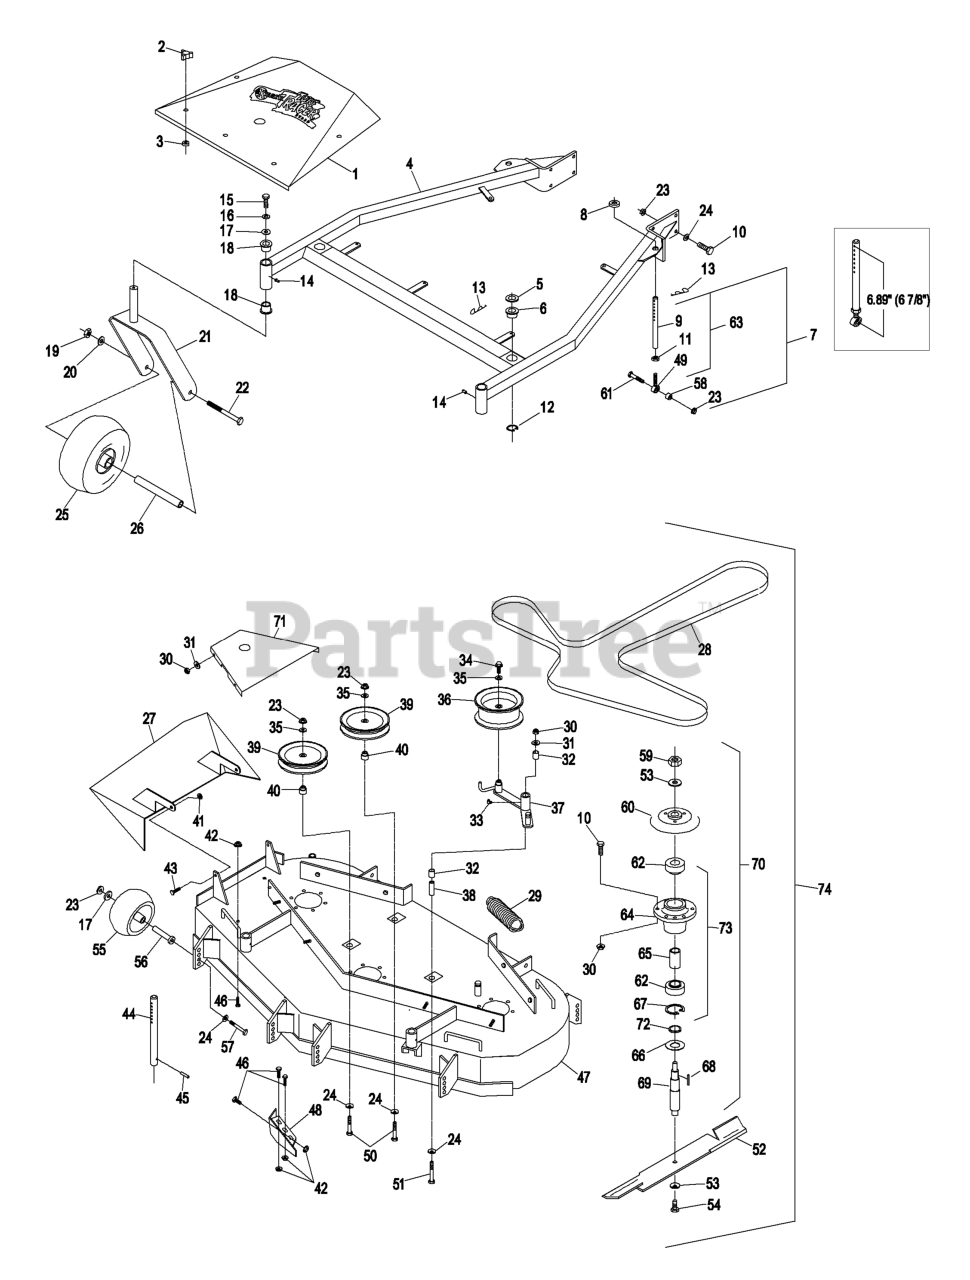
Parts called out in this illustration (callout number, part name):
2	KNOB-3 PRONG
4	SUPPORT,DECK W/BUSHINGS
5	SPACER-DECK SUPPORT
6	BUSHING-DECK
9	LINK,SUPPORT
10	SCREW-HH
11	NUT-HEX
12	RING-RETAINING
13	PIN,HAIR COTTER
14	FITTING-GREASE
15	SCREW-HH
16	WASHER-LOCK
18	BEARING-FLANGED
19	NUT-HH
20	WASHER-LOCK
22	SCREW-HH
23	NUT-HHF, WHIZ
24	WASHER-BELLEVILLE
27	WLD,CHUTE DISCHARGE
28	BELT,DECK DRIVE
30	NUT-LOCK, NI
31	WASHER-FLAT
32	SLEEVE-BEARING
33	FITTING-GREASE, 90 DEG
34	SCREW-HHF
35	WASHER-FLAT
38	BUSHING-PIVOT, IDLER
39	PULLEY-IDLER
40	BUSHING-IDLER
41	NUT-LOCK, NI
43	SCREW-HH
44	ROD,DECK SUPPORT
46	SCREW-HH
47	ASM,DECK W/DECALS TTHP52
48	WLD,BAFFLE DISCHARGE
49	BALLJOINT
50	SCREW-HH
51	SCREW-HH
53	WASHER-SPRING
54	SCREW-CAP
55	ROLLER-SCALP, ANTI
56	BUSHING-ROLLER
57	SCREW-HH
59	NUT-HEX
60	SHEAVE,W/HUB 5.72
61	SCREW-HH
62	BEARING
65	SPACER-BEARING
66	GUARD-BEARING, BOTTOM
67	RING-SNAP
68	KEY-RECTANGLE
69	SHAFT,SPINDLE
70	HOUSING,CUTTER COMPLETE
72	SPACER-PULLEY/BEARING
74	Assembly, Cutting Deck Complete
